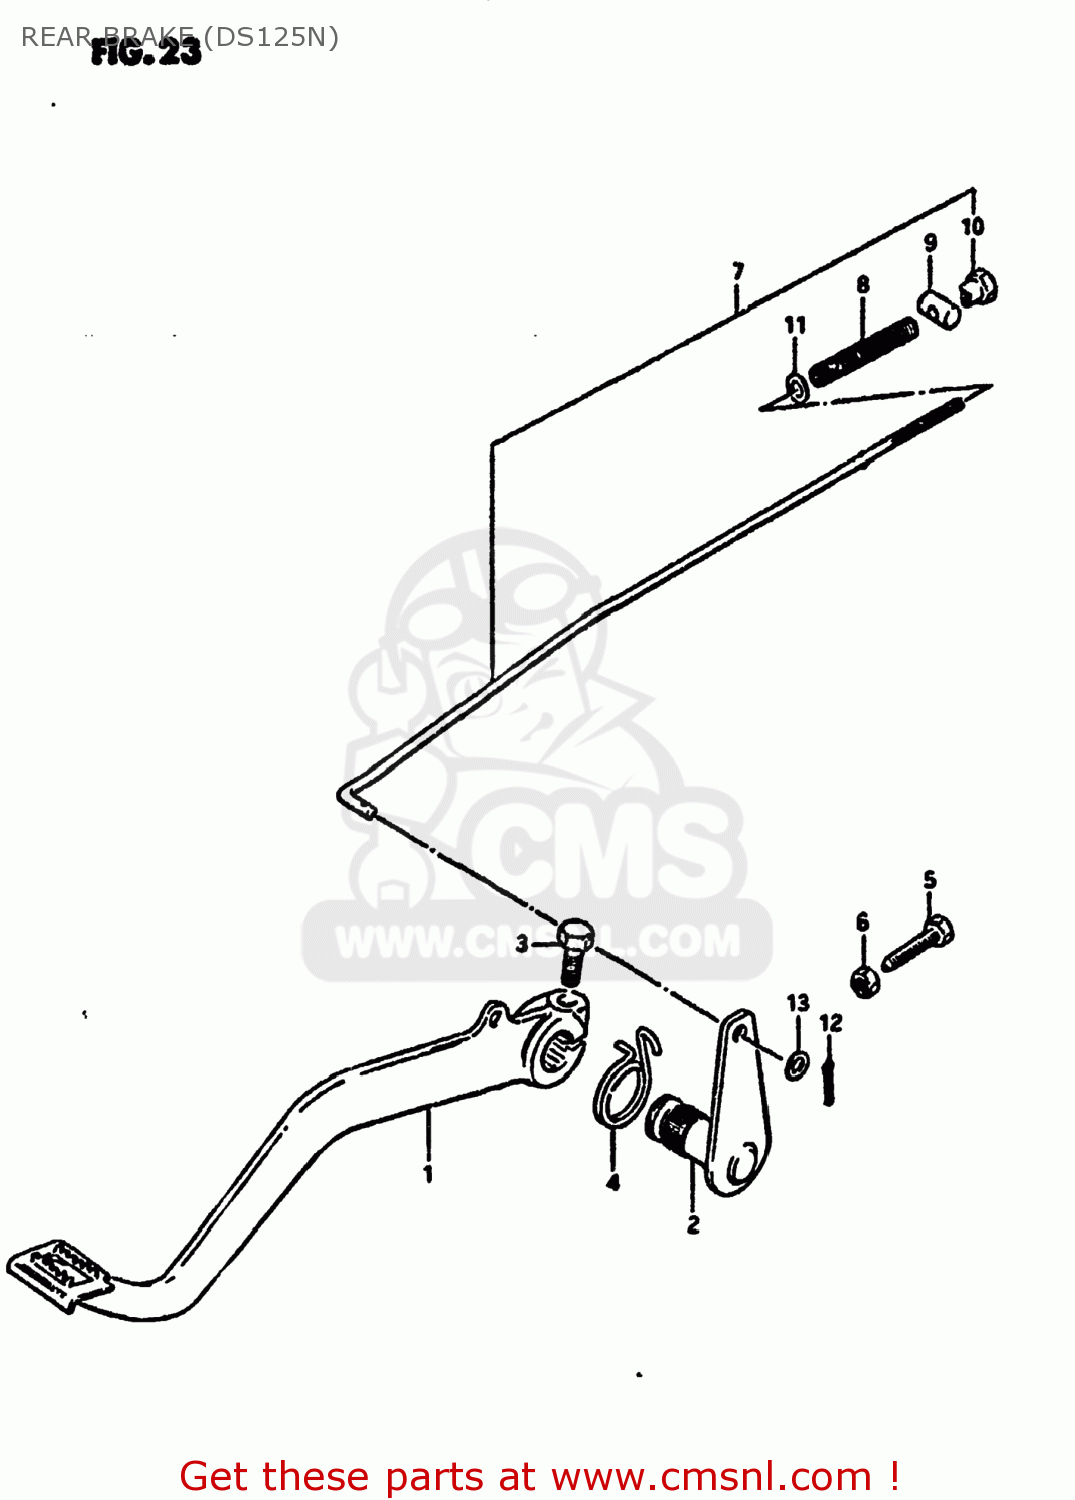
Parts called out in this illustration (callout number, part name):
1	PEDAL,BRAKE
2	ARM,BRAKE PEDAL ROD
3	BOLT
4	SPRING
5	BOLT(6X23)
6	NUT
7	ROD ASSEMBLY,REAR BRAKE
8	SPRING
9	PIN(11X18)
10	NUT
11	WASHER
12	PIN 20X20
13	WASHER
